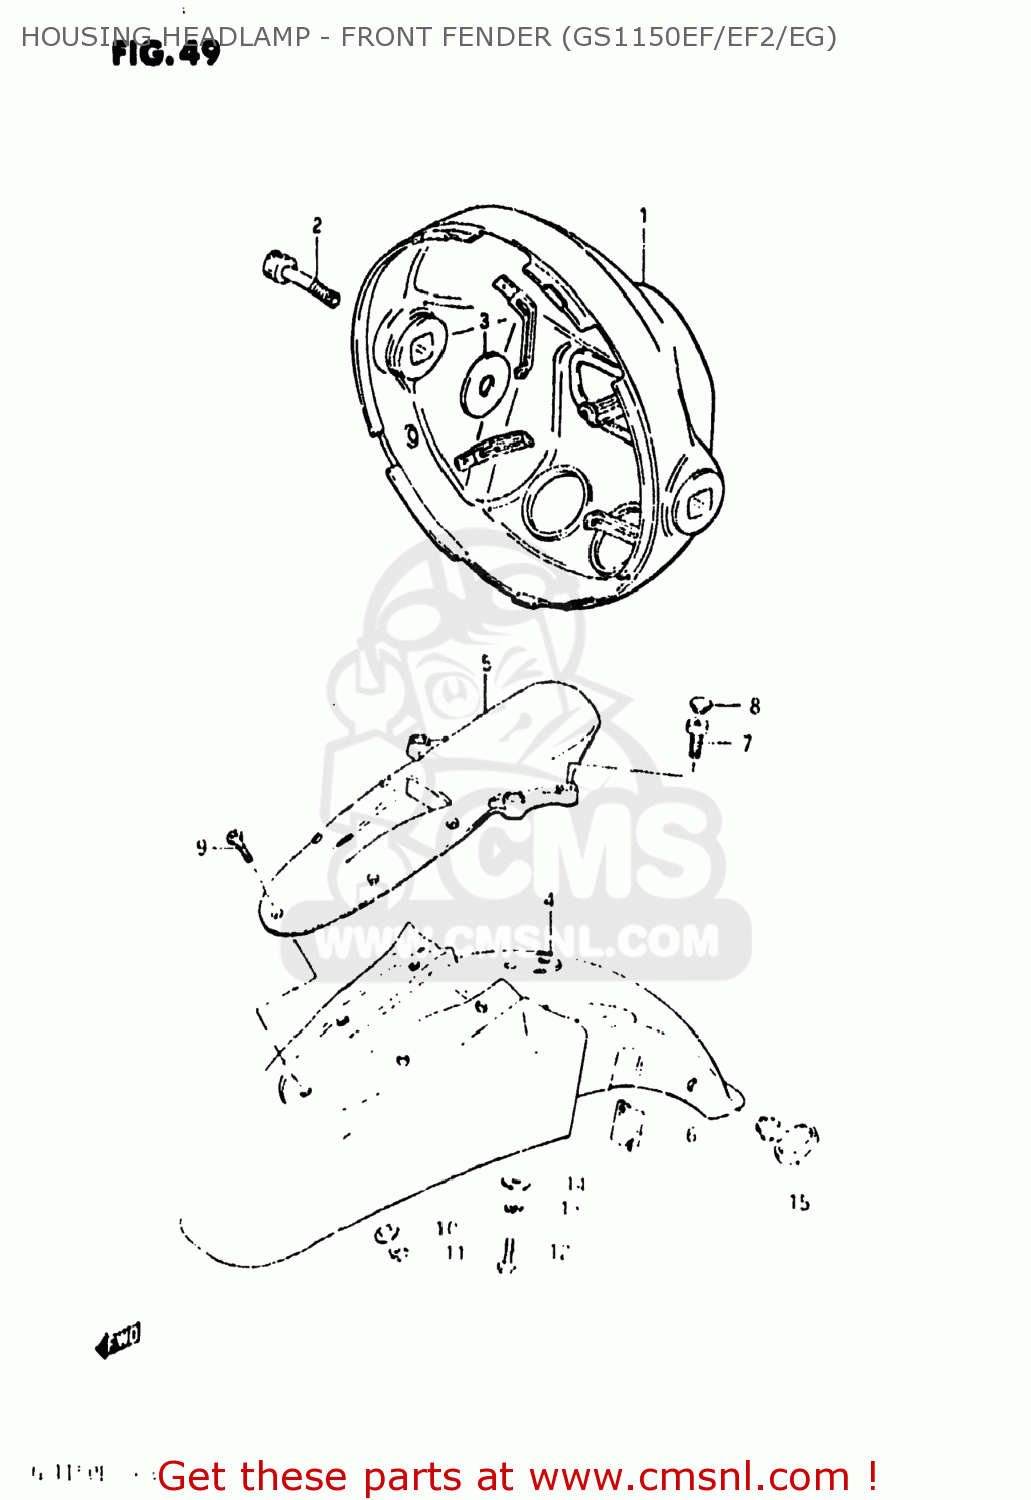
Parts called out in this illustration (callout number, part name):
1	HOUSING,HEADLAMP(BLACK)
2	BOLT, LH
3	WASHER (8.5X29X1.6)
4	FENDER,FRONT
5	BRACE,FR FENDER CTR
6	CUSHION
7	BOLT
8	CAP(OD:14.5)
9	SCREW, CENTER
10	WASHER
11	NUT 8MM
12	BOLT, UPPER
13	LOCK WASHER
14	WASHER
15	GUIDE,CABLE
